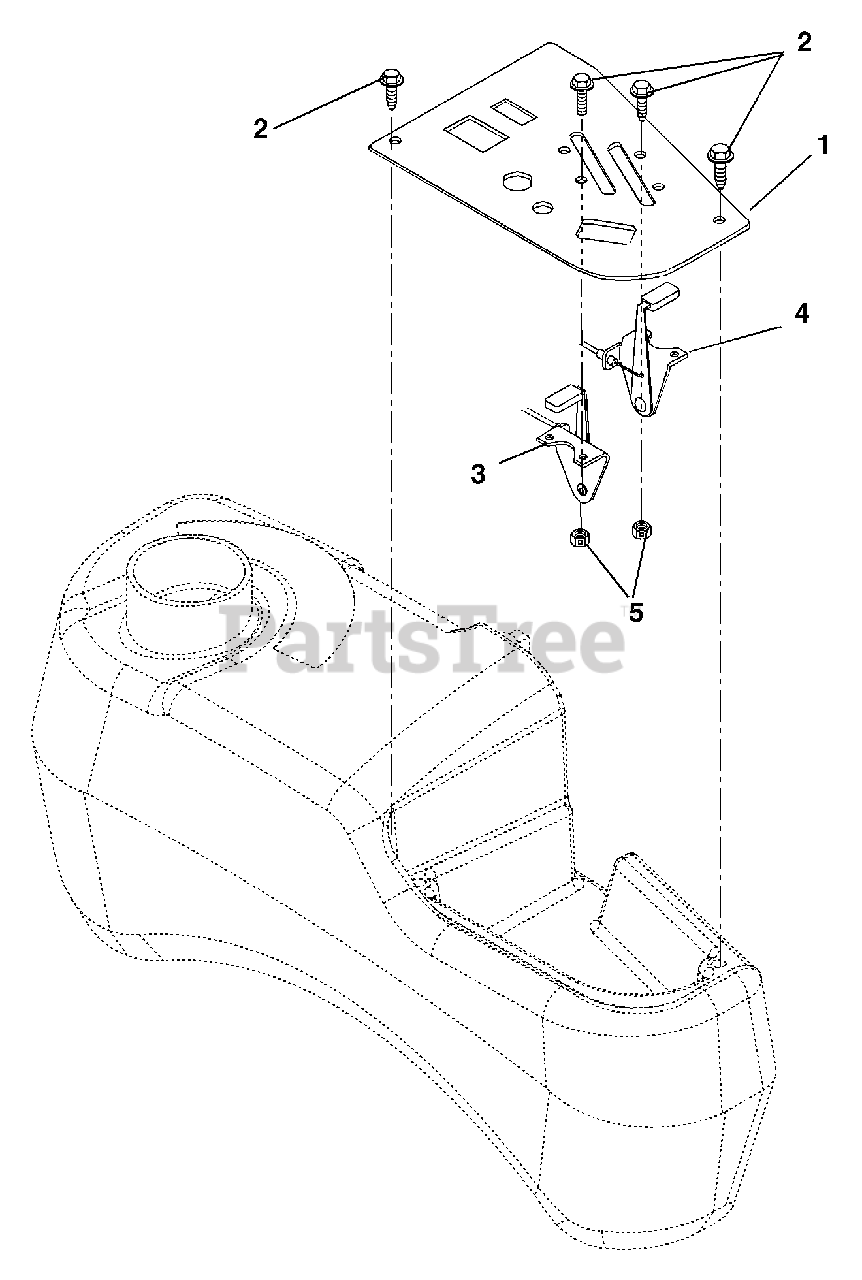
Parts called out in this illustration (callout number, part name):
1	Panel-Control
2	Screw-Machine 10-24 x .50 Hex Washer Head
3	Cable, Throttle
4	Cable, Choke
5	Nut-Locking-Nylon 10-24 With Insert
